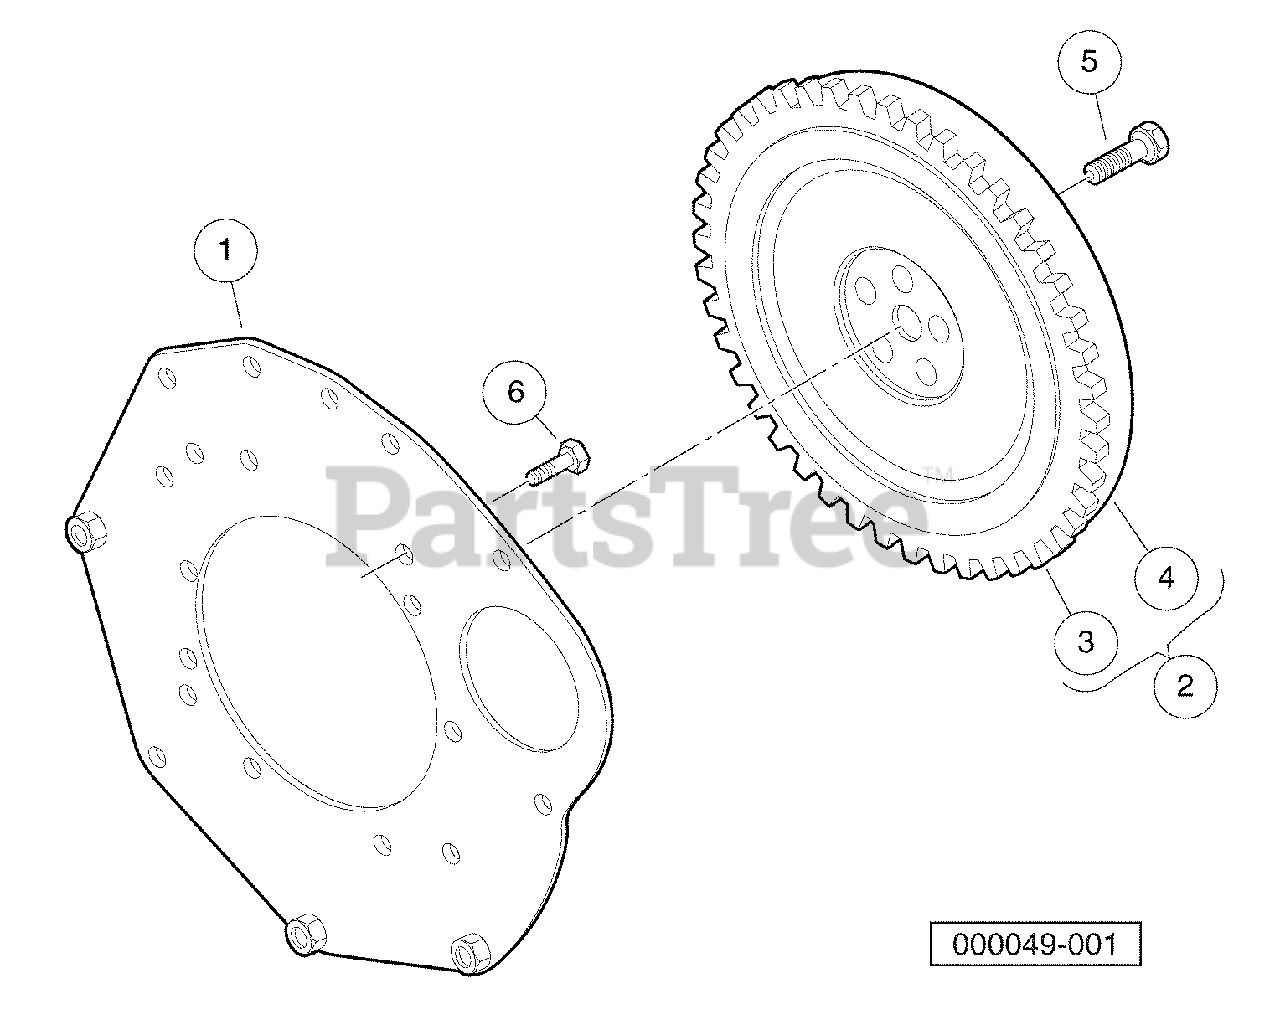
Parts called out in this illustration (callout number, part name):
1	Plate, Rear End
2	Flywheel
3	Gear, Ring, D722
4	Flywheel
5	Bolt, Flange Head, M10 X 1.5 X 25
6	Bolt, End Plate
